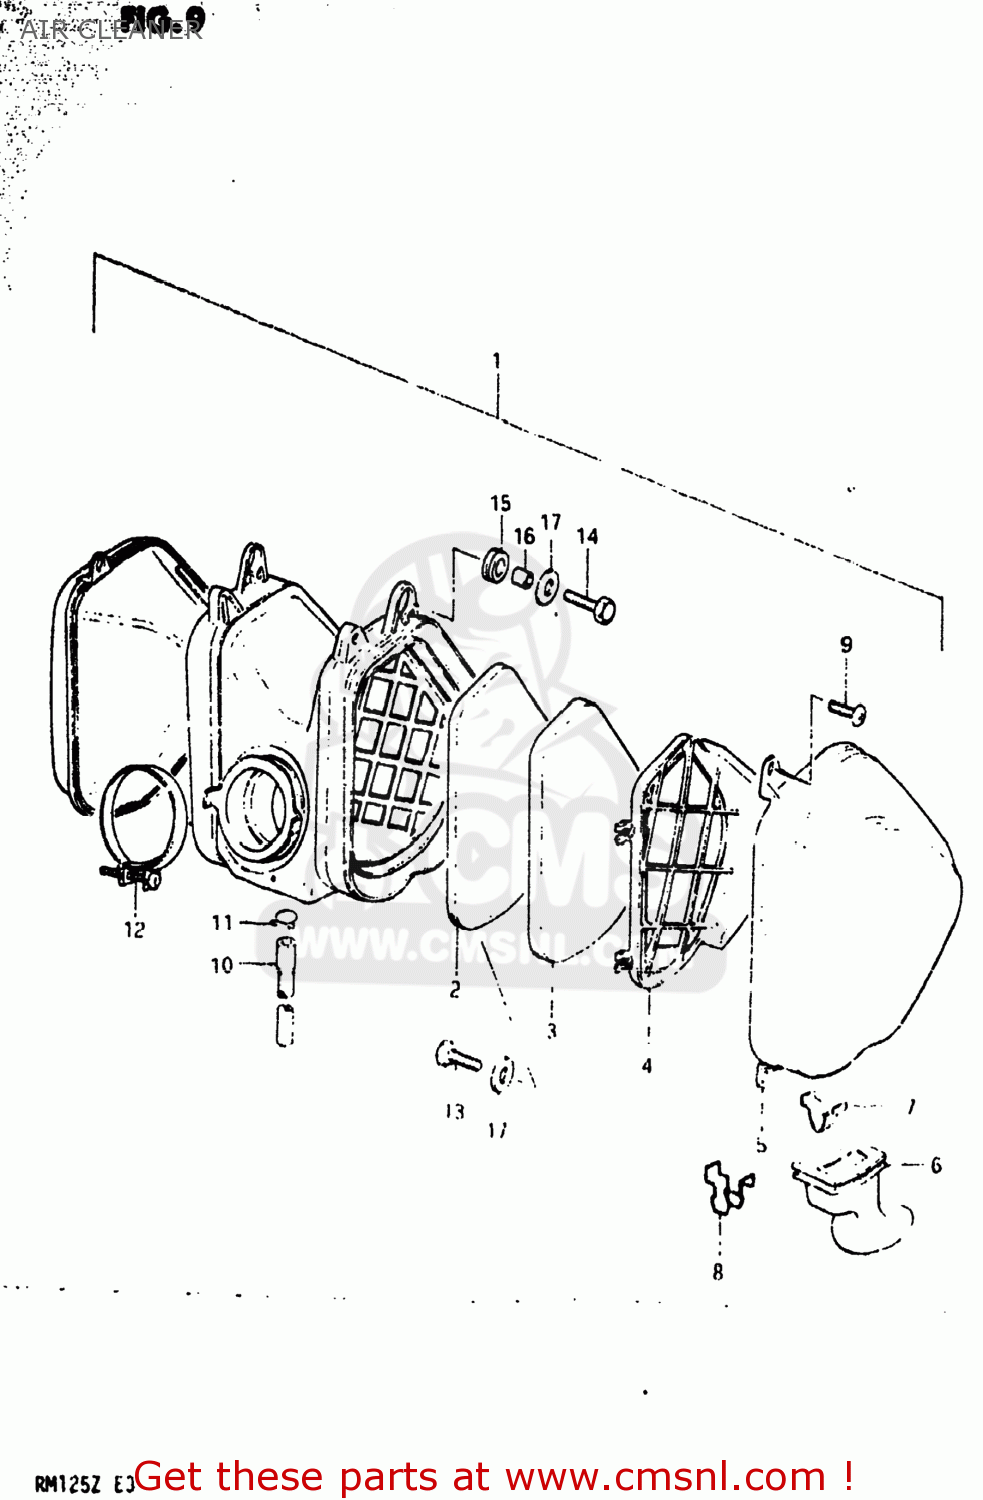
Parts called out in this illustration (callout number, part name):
1	CLEANER ASSEMBLY,AIR
2	FILTER,L
3	FILTER,2ND,R
4	HOLDER,FILTER
5	CAP,AIR CLEANER
6	DRAIN TUBE
7	DRAIN STOPPER
8	DRAIN STOPPER
9	SCREW
10	DRAIN TUBE
11	CLIP
12	CLAMP
13	BOLT, UPPER
14	BOLT
15	CUSHION
16	SPACER (7X9X7)
17	WASHER
